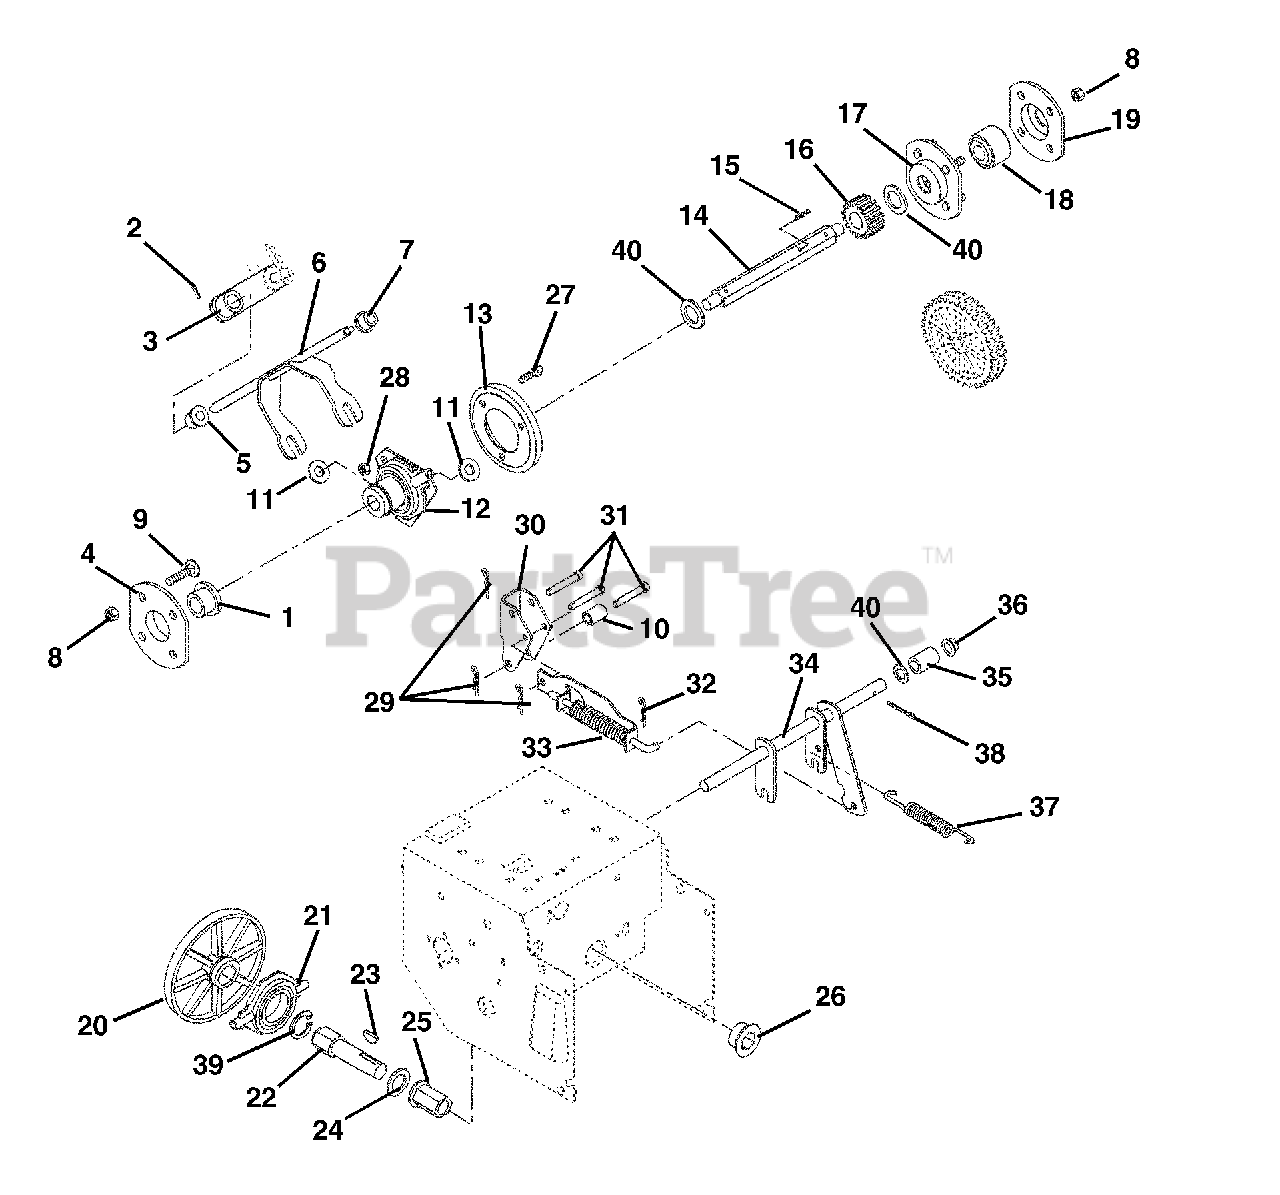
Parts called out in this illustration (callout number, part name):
1	BSHG-FLG .500X.750X.625X.937
2	PIN-ROLL .156X.88
3	ARM, SPEED CONTROL
4	FLANGE AND BUSHING
5	BSHG-FLG.500X.625X.312X.750NY
6	FORK-SPEED
7	BSHG-FLG .325X.444X.440X.560
8	NUT-LK-DUAL FACE 10-24 YWZC
9	BLT-RDHDSQSHK #10-24X.38 GR2YW
10	SPACER .322X.626X.50
11	WSHR-FL-STL .505X1.00X.062YWZC
12	SHIFT CARRIER
13	DISC, FRICTION - 730 MAT'L
14	HEX SHAFT
15	PIN-ROLL .125X.88
17	BEARING FLANGE
18	BRG-BALL .500X1.38X.437
19	BEARING FLANGE
20	FRICTION PLATE
21	BEARING ASSEMBLY
22	HEX SHAFT
23	KEY-WDRF .188X.75X.313 SAE 9
24	WSHR, THRUST .625X1.125X.063
25	BSHG-FLG .625X.875X1.750X1.188
26	BSHG-FLG .875X1.25X.75X1.50HX
27	@BLT-HEX .25-20X.50 GR5 YWZC
28	@NUT-LK-CTR .25-20 YWZC
29	PIN-HAIR INT .06X.18X.77
30	BRACKET, TRACTION ARM
31	PIN,CLEVIS .243/.248 X 1.38 YZ
32	PIN-HAIR INT .08X.18X1.18 YWZC
33	TRACTION CLUTCH ASSY
34	CLUTCH FORK
35	SPACER .504X.748X.321
36	CAP, .50 ROD YWZC
37	SG-TENS .063X.44X1.56
38	@PIN-CTR .12X1.00 EXTPRSQCT YZ
39	RG-RTNG-EXT 1.250X.050
40	@WSHR-FL-STL.531X1.06X.095YWZC
